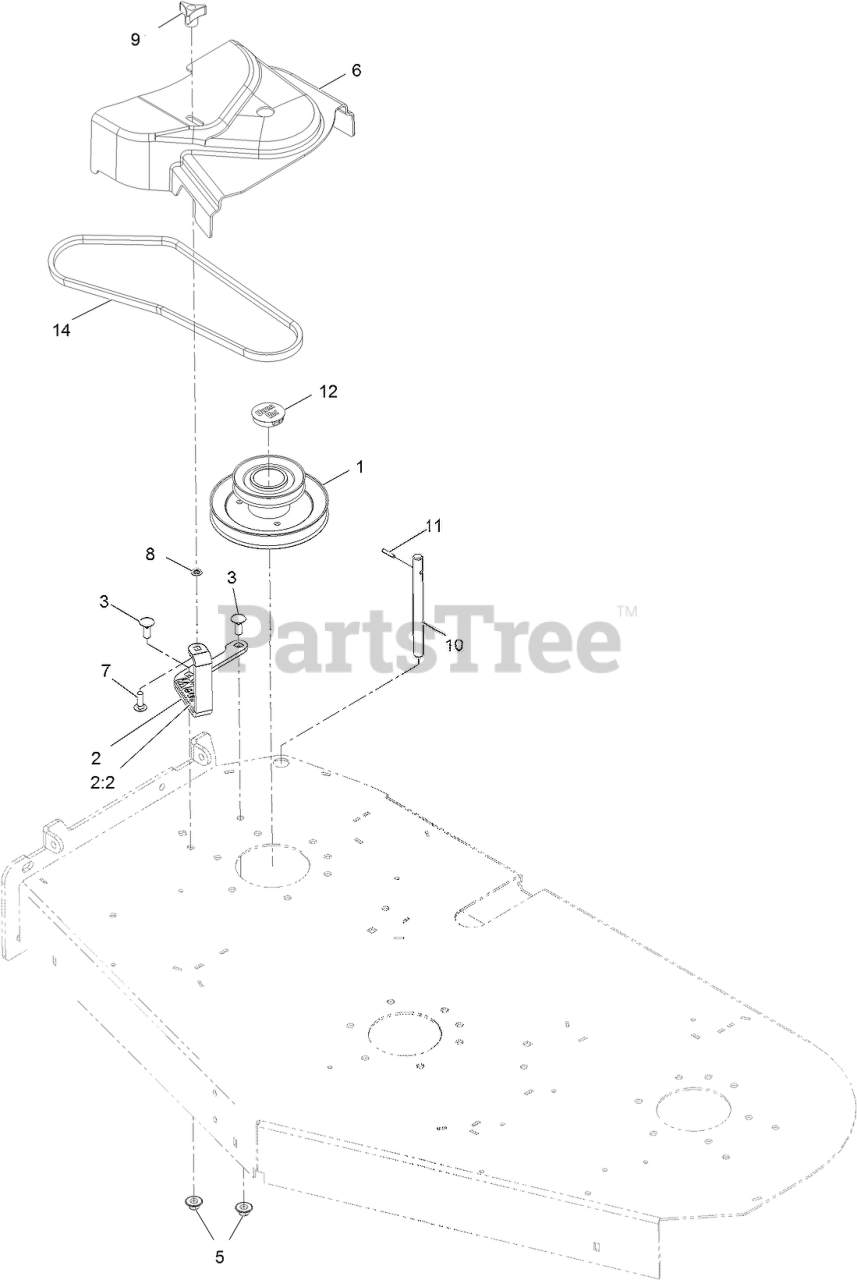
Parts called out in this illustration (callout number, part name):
1	JACKSHAFT-UV DRIVE 523
2	ASM-CVR BRKT W/DECAL
2:2	DECAL-DANGER
3	BOLT-CARR
5	Nut-Nyloc 3/8-16 Flg
6	COVER-BELT, UV 52
7	BOLT-CARR
8	RING-RETAINING, BOLT
9	KNOB-3 PRONG
10	SHAFT-CATCHER, GRASS
11	PIN-ROLL
12	PLUG, BLACK NYLON 1.75
